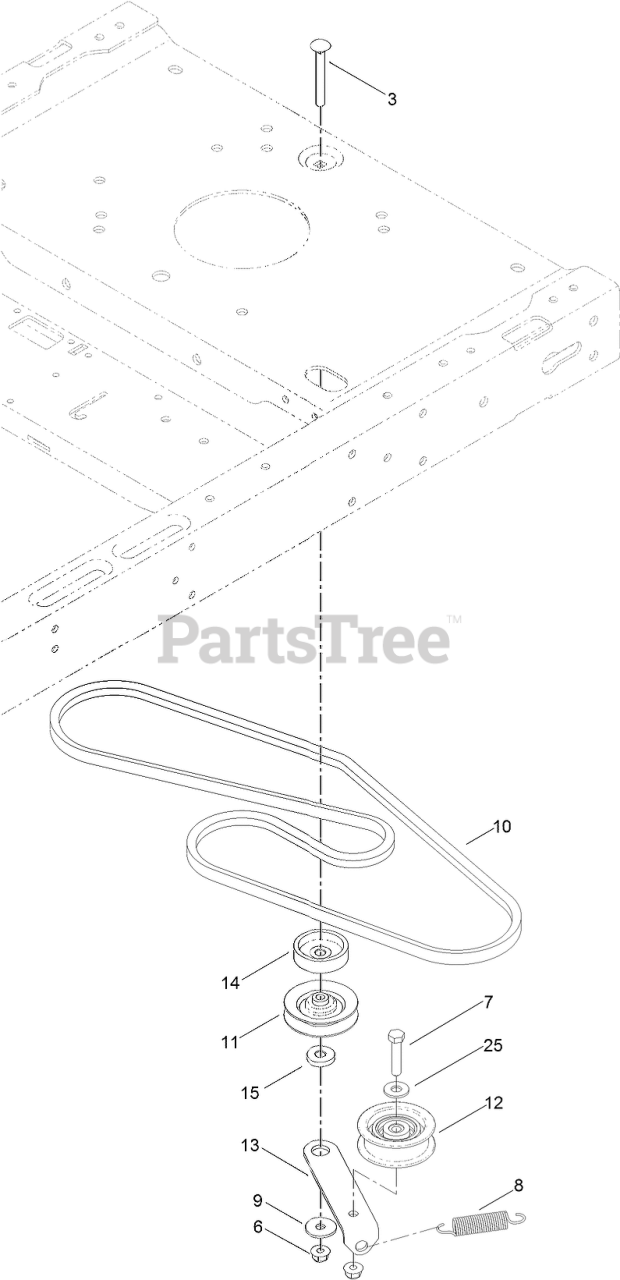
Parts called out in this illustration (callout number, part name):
3	SCREW-CARR
6	NUT-HF, NI
7	SCREW-HH
8	SPRING-RETURN, PEDAL
9	WASHER-PIVOT
10	V-BELT
11	PULLEY-IDLER
12	PULLEY-IDLER
13	ARM-IDLER
14	SPACER
15	SPACER-ARM, IDLER
25	WASHER-FLAT
